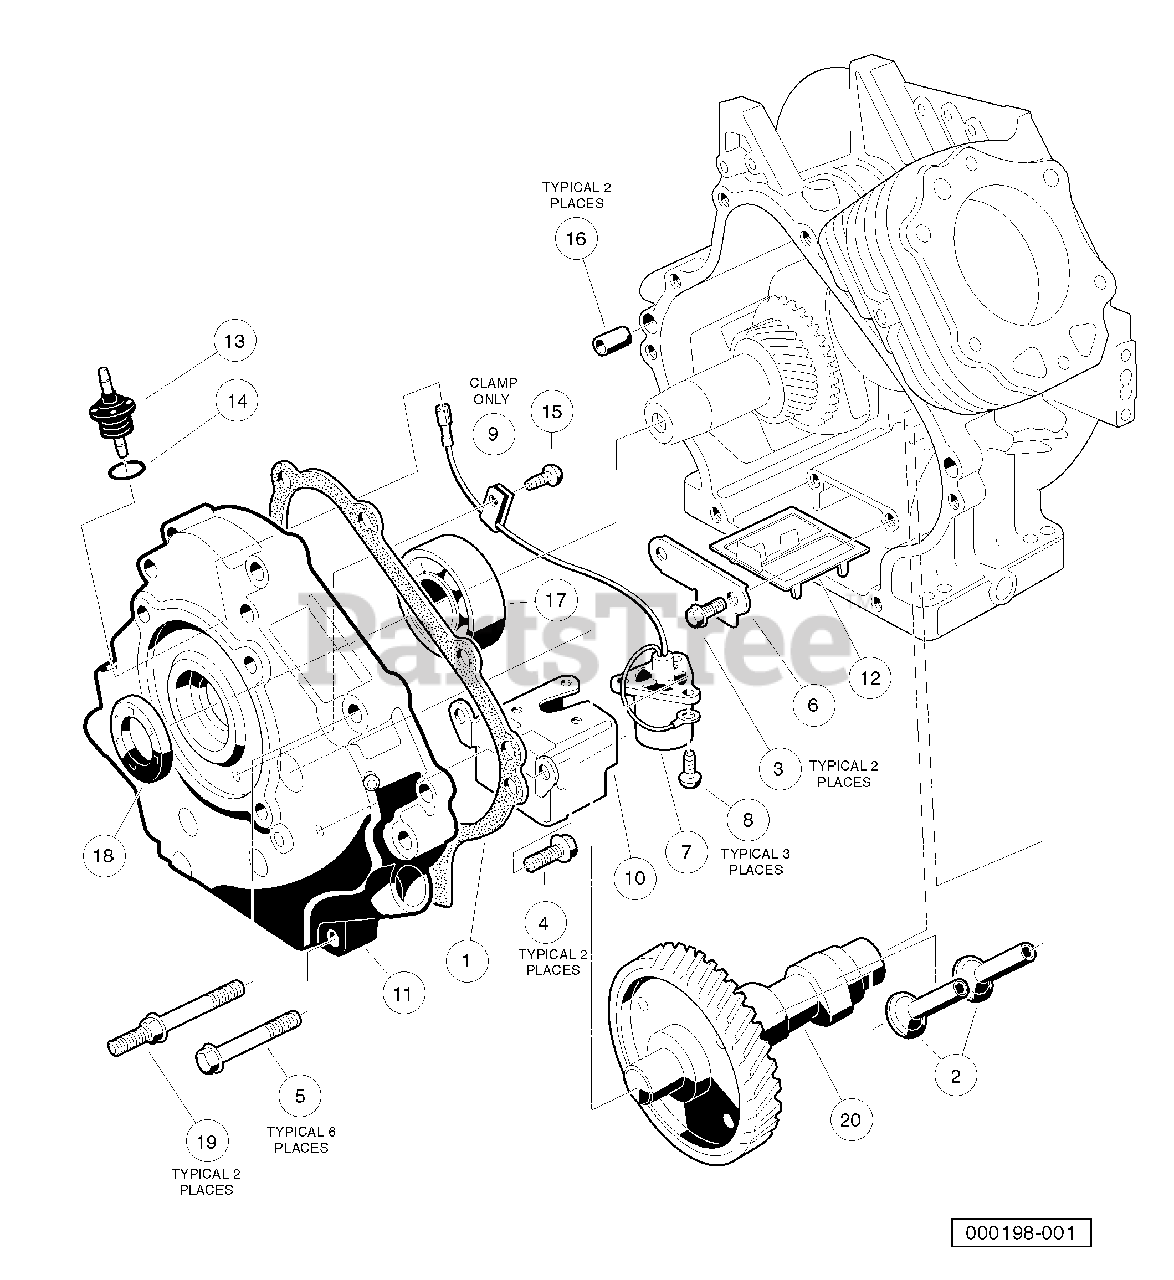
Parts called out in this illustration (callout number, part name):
1	Gasket, Crankcase Cover
3	Bolt, Flange Head, M5 x 0.8 x 8 mm
4	Bolt, Flange Head, M6 x 1 x 12 mm
5	Bolt, Flange Head, M8 x 1.25 x 45 mm
6	Plate, Oil Filter Screen
7	Sensor, Oil Level
8	Screw, Cross Pan-Head, M4 x 0.7 x 8 mm
10	Bracket, Switch, Oil Level
11	Cover, Crankcase
12	Screen, Oil Filter
13	Connector, Cord
17	Bearing, Ball
18	Seal, Crankshaft
19	Bolt, Two-Ended, M8 x 1.25 x 69 mm
20	Camshaft Complete, FE290
